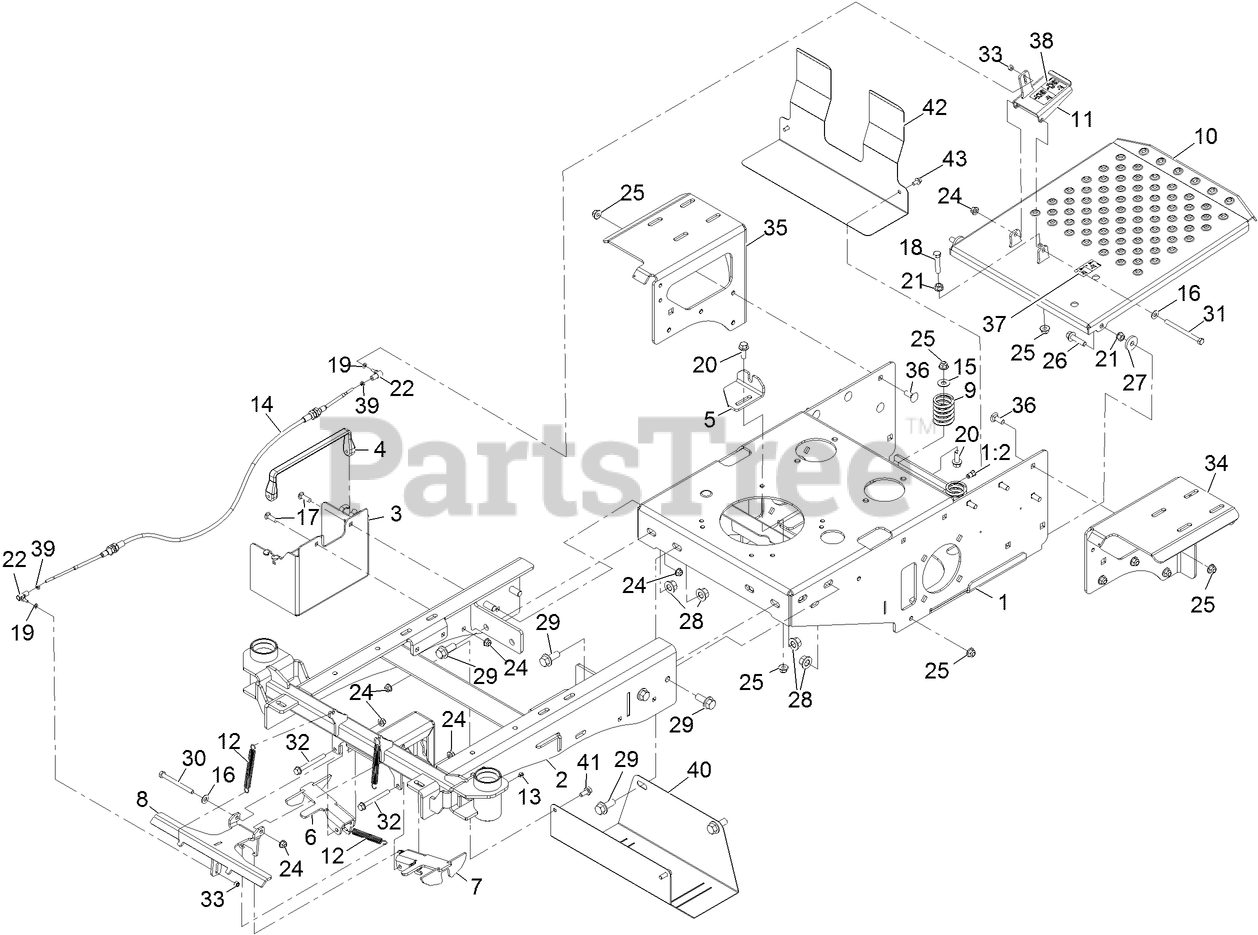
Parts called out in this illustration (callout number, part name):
1	FRAME-REAR
1:2	NUT-CLINCH,HEX
2	WLD, FRONT FRAME, JR36 24 GALLON UNIT
3	BOX-BATTERY
4	STRAP, TARP
5	BRACKET-CABLE, LOWER
6	WING-CAPTURE, RT
7	WING-CAPTURE, LT
8	WLD, CAPTURE, T-BAR, JR36
9	SPRING-COMPRESSION
10	WLD, FOOT PLATE, JR36
11	WLD, FOOT PEDAL, LCS
12	SPRING-EXTENSION
13	FITTING-GREASE, ZERK
14	CABLE-CASTER, LOCKING
15	WASHER-FLAT
16	WASHER
17	BOLT,CARRIAGE,5/16-18X1,ST/ST 18-8
18	SCREW-HH
19	WASHER-FLAT
20	SCREW-HHF
21	NUT-HEX FLANGE
22	BALL JOINT-SS
24	NUT-HEX FLANGE
25	NUT-HEX FLANGE
26	SCREW-HHF
27	WASHER
28	NUT-HEX FLANGE
29	SCREW-HHF
30	SCREW-HH
31	SCREW-HH
32	SCREW-HHF
33	NUT-NYL LOCK,#10-32,ST/ST 18-8
34	WLD, MOUNT, FERT BOX, L, JR36
35	WLD, MOUNT, FERT BOX, R, JR36,
36	SCREW-CARR
37	DECAL-BUTTON, FOOT (SPRAY)
38	DECAL-LOCK, CASTER
39	NUT-HEX, JAM
40	GUARD, MUFFLER, JR36
41	SCREW-HHF
42	SHIELD, HEAT, HYD PUMP, JR36
43	SCREW-HHF
